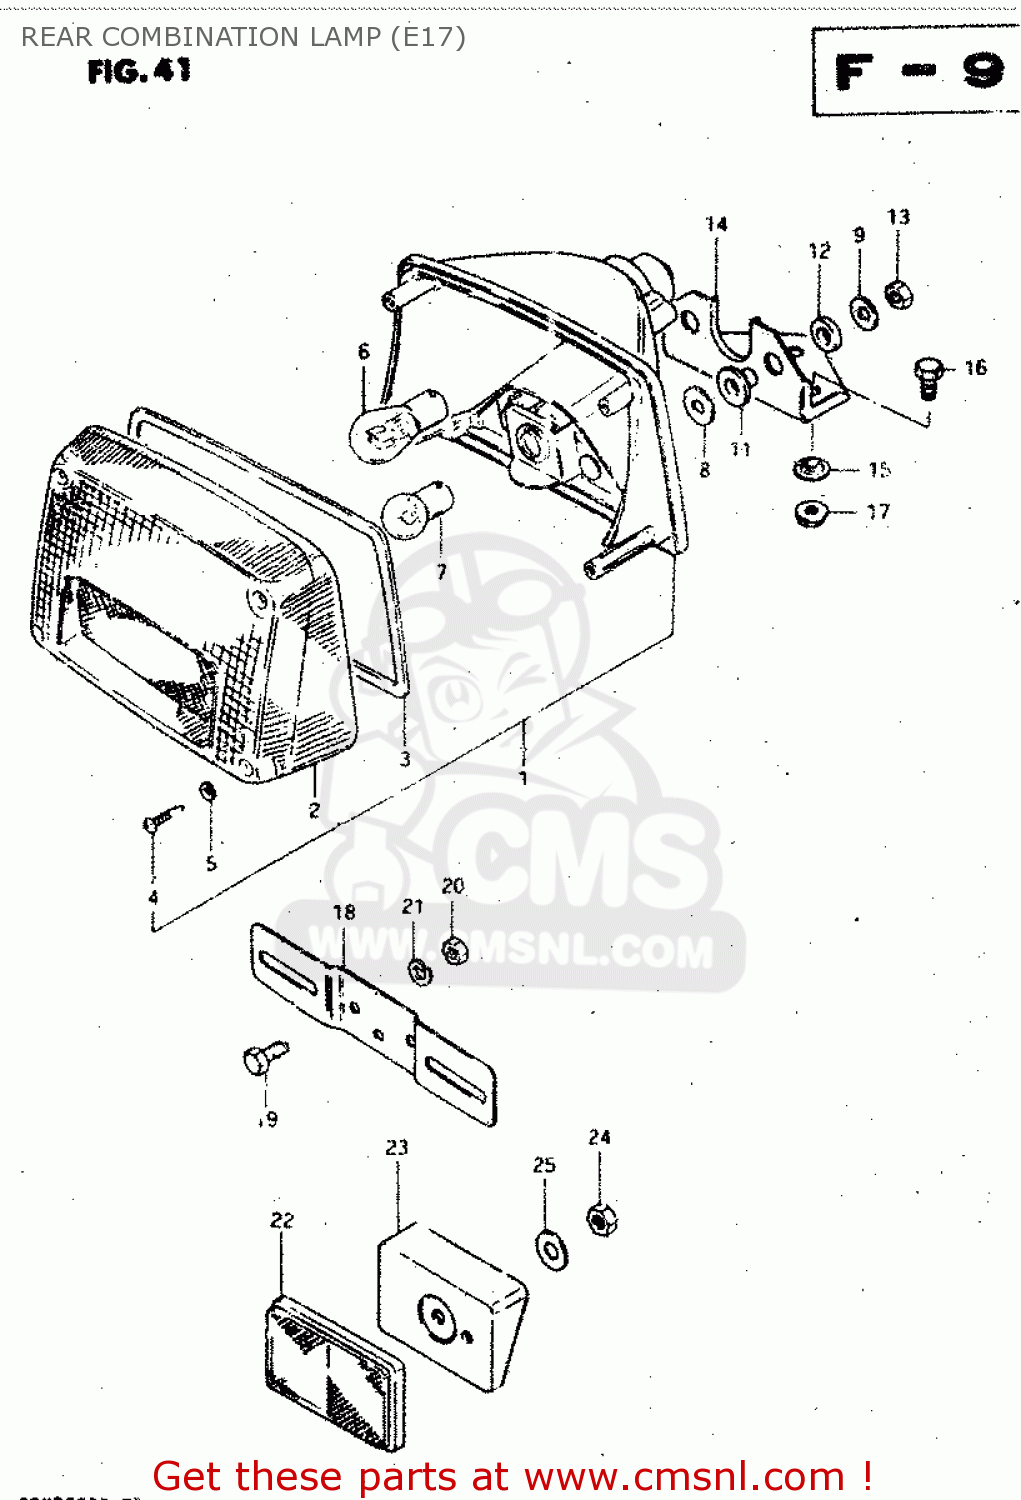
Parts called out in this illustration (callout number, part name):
1	LAMP ASSY, TAIL
2	LENS
3	GASKET (NAS)
4	SCREW,REAR COMBINATION LAMP
5	GASKET (NAS)
6	BULB 12V21/5W
7	BULB
8	WASHER
9	WASHER(6,5X22X1.6)
10	SPACER(6.1X9X7.5)
11	CUSHION
12	CUSHION
13	NUT 6MM
14	BRACKET,RR COMBINATION LAMP
15	WASHER
16	BOLT, UPPER
17	NUT 6MM
18	PLATE,RR LICENSE
19	BOLT
20	NUT
21	LOCK WASHER
22	REFLECTOR,REFLEX
23	SPACER
24	NUT
25	WASHER(5.2X16X1)
